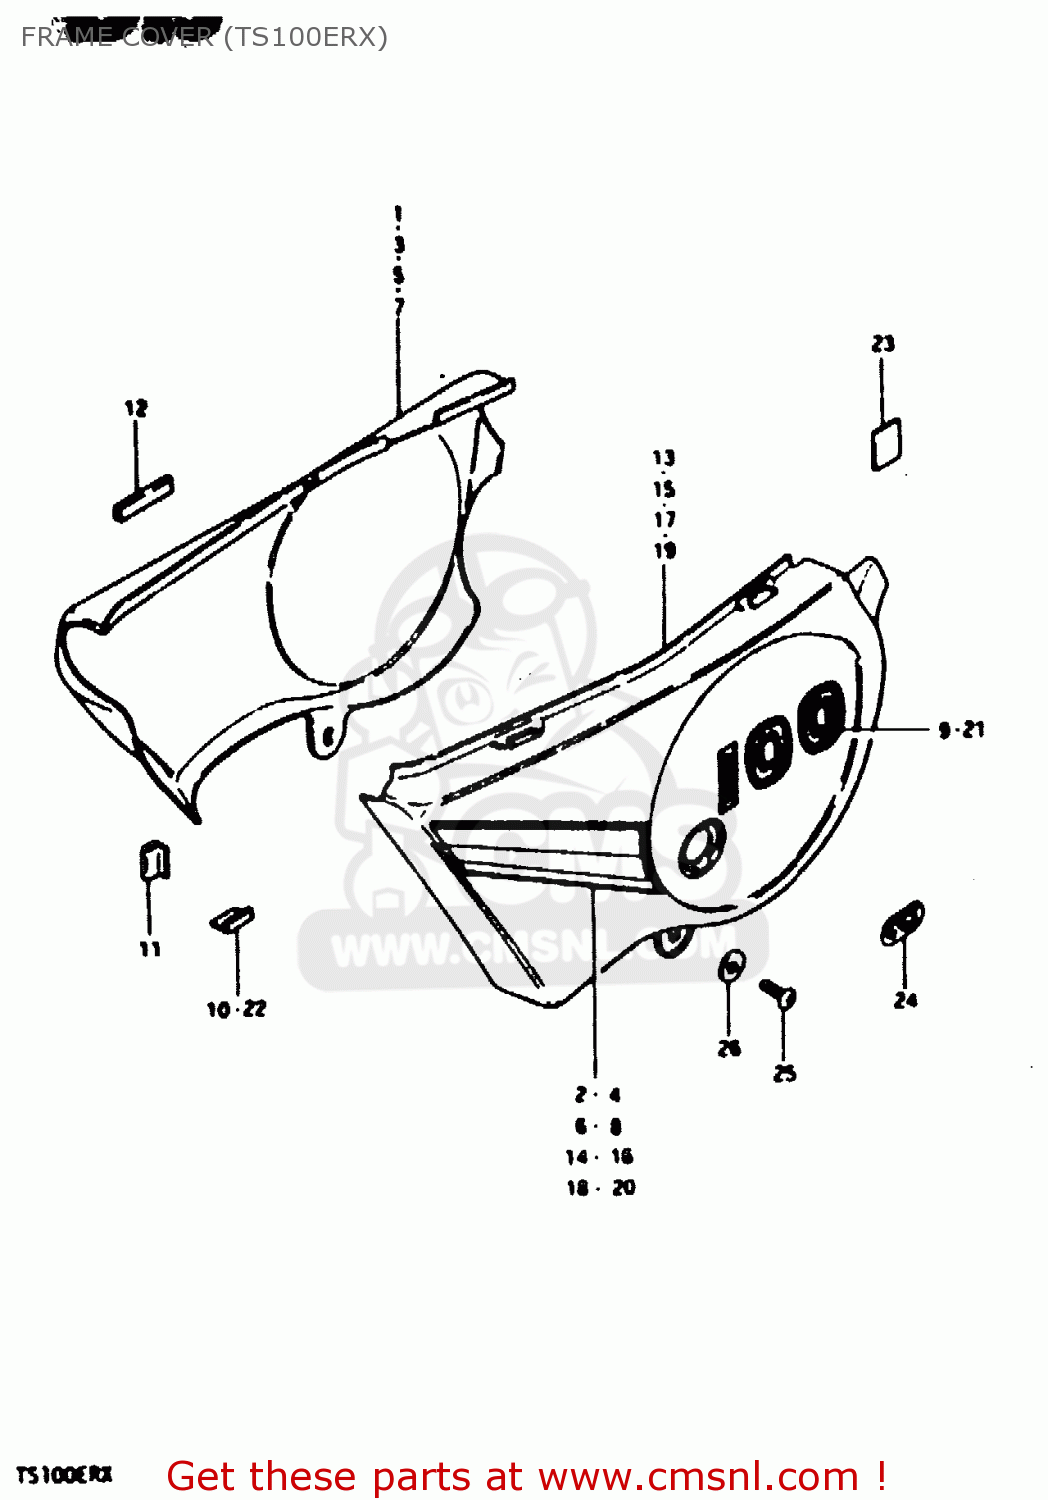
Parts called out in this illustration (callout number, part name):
1	COVER, FRAME RH (RED)
2	TAPE, RH
3	COVER,FRAME,RIGHT
4	TAPE, RH
5	COVER, FRAME RH (WHITE)
6	TAPE, RH
7	COVER, FRAME RH (YELLOW)
8	TAPE, RH
9	EMBLEM, "100" RH (WHITE)
10	CUSHION,FRAME COVER
11	CUSHION,FRAME COVER
12	CUSHION,FRAME COVER
13	COVER, FRAME LH (RED)
14	TAPE, LH
15	COVER,FRAME,LEFT
16	TAPE, LH
17	COVER, FRAME LH (WHITE)
18	TAPE, LH
19	COVER, FRAME LH (YELLOW)
20	TAPE, LH
21	EMBLEM, "100" LH (WHITE)
22	CUSHION,FRAME COVER
23	PROTECTOR(170X95X3.0)
24	EMBLEM,CCIS
25	SCREW
26	WASHER
